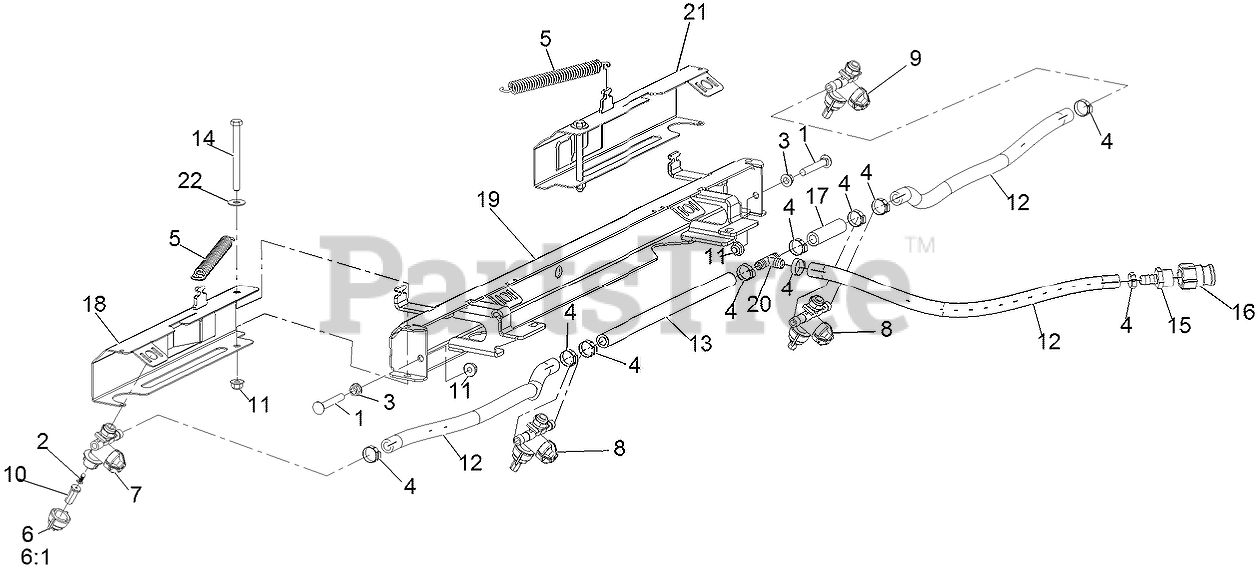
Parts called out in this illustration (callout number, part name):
1	SCREW-CARR
2	STRAINER-NOZZLE, 50M 5PSI
4	CLAMP-OETIKER, 167
5	SPRING-EXTENSION
6	CAP-NOZZLE
6:1	SEAT-GASKET
7	BODY-NOZZLE, LEFT
8	BODY-NOZZLE, CENTER
9	BODY-NOZZLE, RIGHT
10	TIP-SPRAY
11	Nut-Hex Flange
12	HOSE-SPRAY
13	HOSE-SPRAY
14	SCREW-HH
15	FITTING-STRAIGHT
16	ADAPTER-MALE
17	HOSE-SPRAY
18	WING-BOOM LH
19	WLD, BOOM, CENTER, ZPLUG
20	FITTING-TEE, BARB
21	WING-BOOM RH
22	WASHER-FLAT
